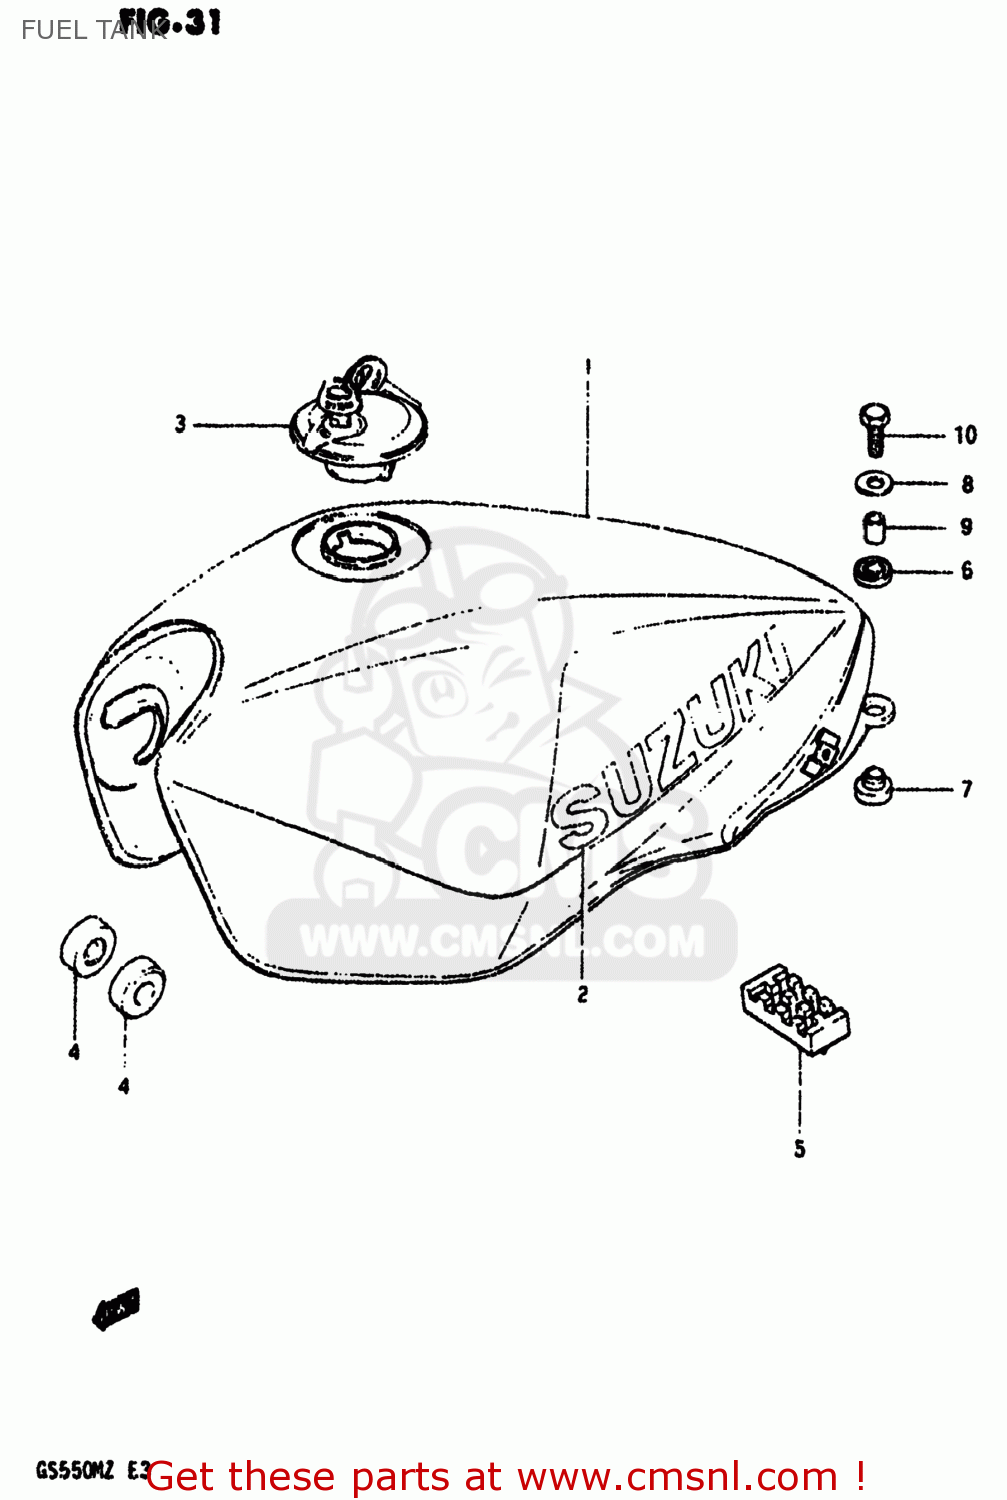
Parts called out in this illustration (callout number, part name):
1	TANK ASSEMBLY,FUEL
2	EMBLEM
3	CAP SET,FUEL TANK
4	CUSHION
5	CUSHION,FUEL TANK CTR
6	CUSHION
7	CUSHION
8	WASHER (6.5X24X1.6)
9	SPACER
10	BOLT
